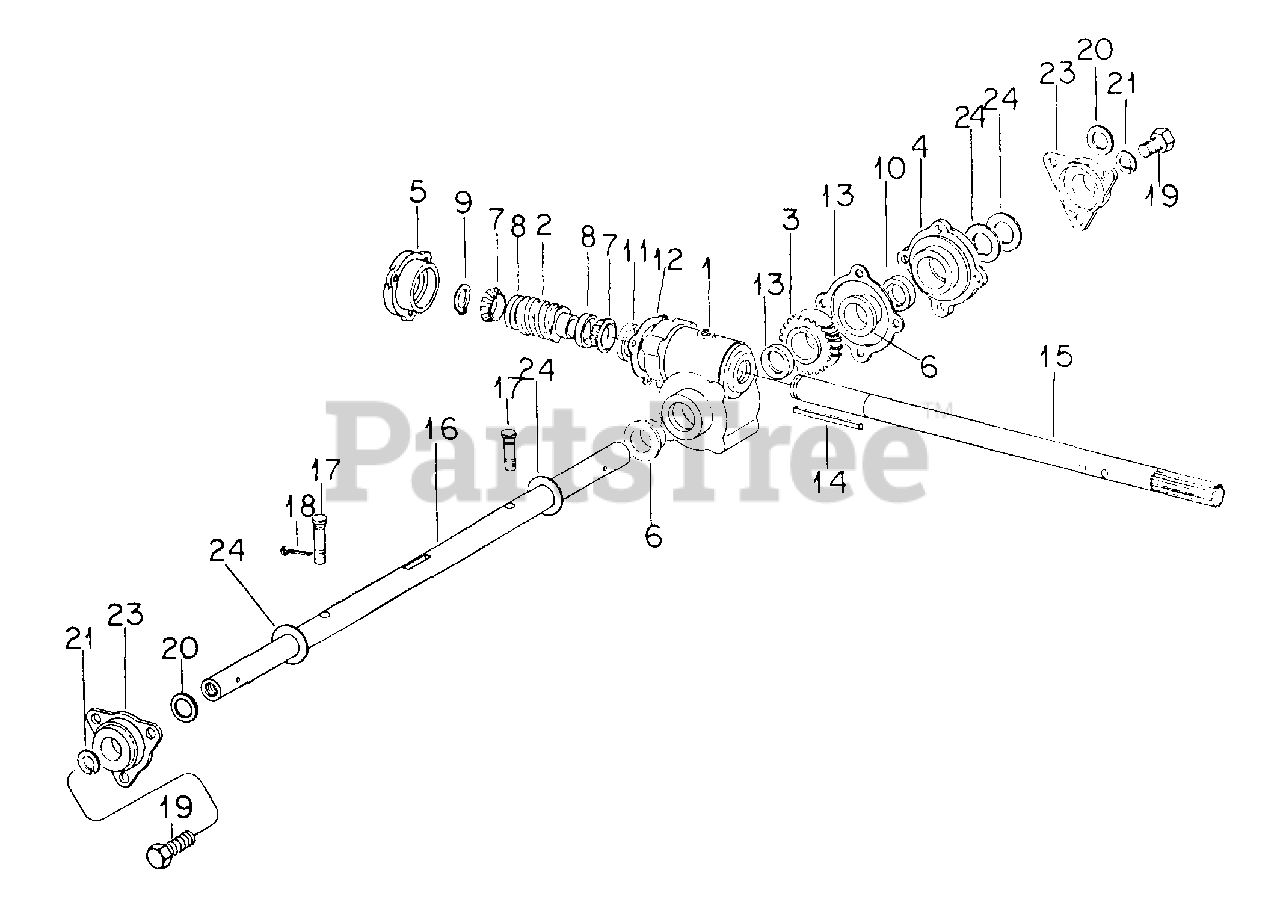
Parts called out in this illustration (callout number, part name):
2	WORM, DOUBLE THREAD
3	GEAR, LH 20 TEETH
6	BUSHING, BRONZE
7	BEARING ASSY, ROLLER CONE
8	BEARING, ROLLER CUP
9	RING, RETAINING
12	SHIM, GASKET - .010
13	SHIM, GASKET - .010
14	KEY, 3/16 X 1-15/16 SQ PARALLEL
15	SHAFT, BLOWER
16	SHAFT, ROTOR
18	PIN, 5/32 X 3/4 COT.
19	SCREW, 1/2-13 X 1 HEX-HD CAP
20	WASHER, 17/32 X 1-1/4 X 16 GA
21	WASHER, 1/2 REG LOCK
23	BEARING, FLANGE
24	WASHER, THRUST
